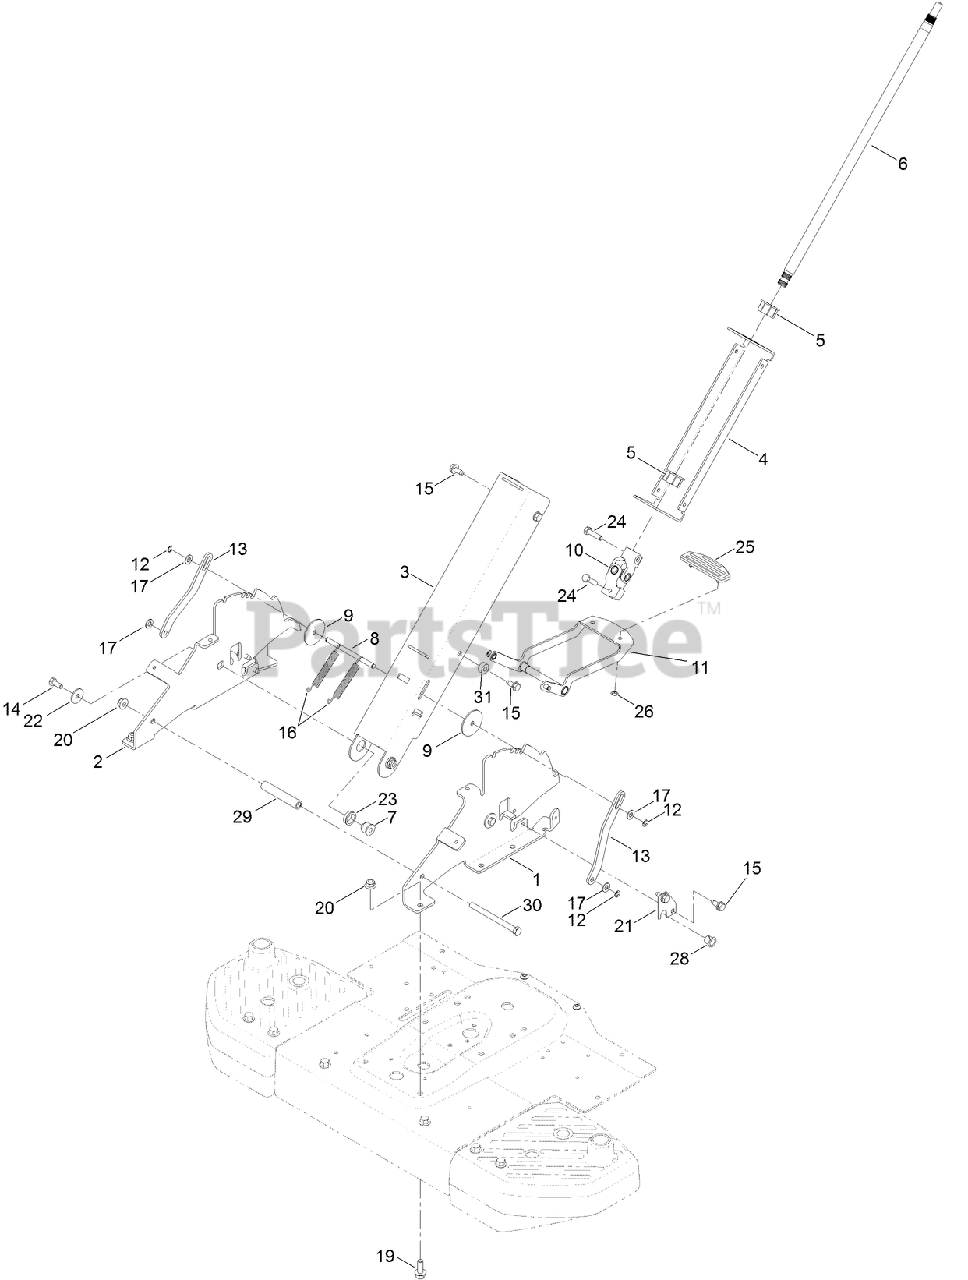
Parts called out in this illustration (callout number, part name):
1	BRACKET-PIVOT, COLUMN (LH)
2	BRACKET-PIVOT, COLUMN (RH)
3	COLUMN-FRONT
4	COLUMN-BACK
5	BUSHING-STEERING, UPPER
6	SHAFT-STEERING, UPPER
7	SPACER-PIVOT, COLUMN
8	ROD-PLUNGER
9	WASHER-SHAFT, TILT
10	U-JOINT ASM
11	RELEASE PEDAL ASM
12	E-RING
13	PLATE-PLUNGER
14	SCREW-HH
15	SCREW-HWHTF
16	SPRING-EXTENSION
17	WASHER-PLAIN
19	SCREW-HHF
20	NUT-HF, NI
21	PLATE-RETAINER
22	WASHER-PIVOT
23	BUSHING-FLANGE
24	SCREW-HH
25	PAD-TILT PEDAL
26	NUT-PUSH
28	BUSHING-NYLINER
29	SPACER
30	SCREW-HH
31	SPACER
